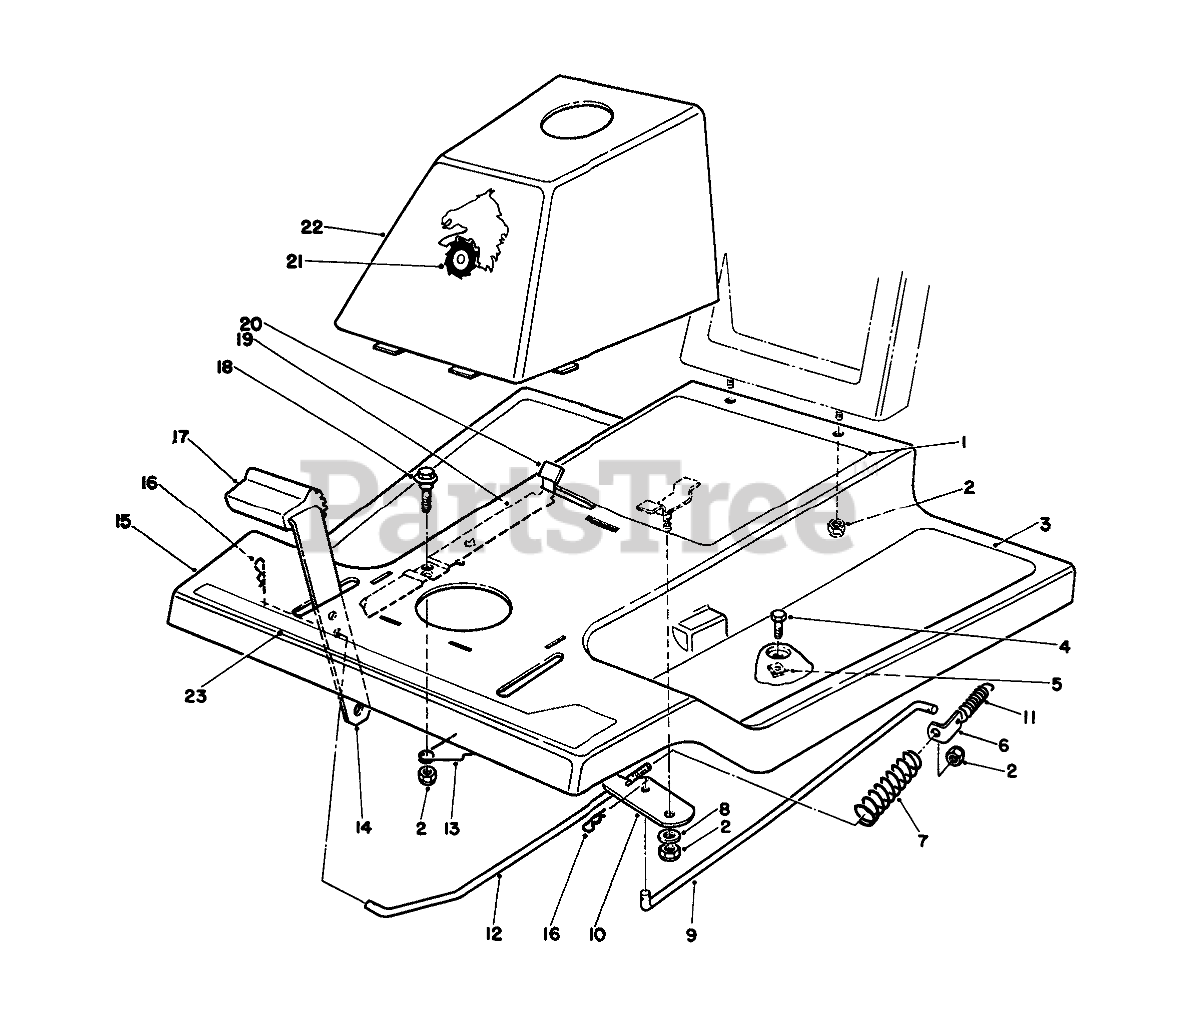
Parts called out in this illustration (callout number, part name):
1	DECAL - INSTRUCTION
2	NUT-LOCK, NI
3	TREAD-FOOT
4	SCREW-HH
5	NUT-TINNERMAN
6	BRACKET-BRAKE RETURN
7	SPRING-TRACTION BRAKE
8	WASHER-PIVOT
9	ROD-TRANS BRAKE
10	Lever-Brake, Bellcrank
11	SPRING-IDLER
12	ROD-FRONT BRAKE
13	SPRING-PARKING BRAKE
14	Pedal-Brake & Clutch
15	Body W.A.-Front
16	PIN-COTTER
17	PAD-PEDAL
18	SCREW-SHOULDER
19	Parking Brake
20	TIP-PARKING BRAKE
21	DECAL - HORSEHEAD
22	Tower (Incl. Ref. #21)
23	85-AL - RECYCLER
